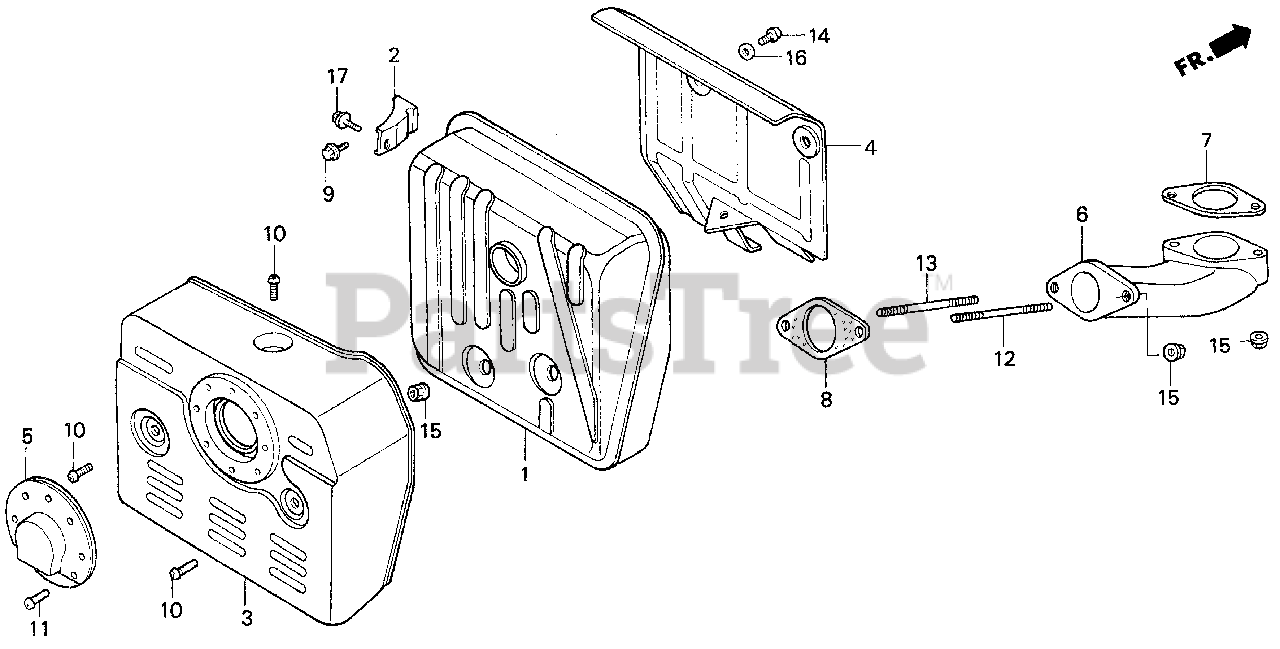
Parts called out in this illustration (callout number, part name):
1	MUFFLER
2	STAY, MUFFLER
3	PROTECTOR, MUFFLER
4	SEPARATOR, MUFFLER
5	CAP, MUFFLER
6	PIPE, EX.
7	GASKET, EX. PIPE (Honda Code 2108090). (NOT AVAILABLE)
7	GASKET, EX. PIPE
7	GASKET, EX. PIPE (WACKER)
8	GASKET, EX. PIPE (Honda Code 2278760). (NOT AVAILABLE)
8	GASKET, EX. PIPE
9	BOLT, FLANGE (8X16)
10	SCREW, TAPPING (5X8)
11	SCREW, TAPPING (4X6)
12	BOLT, STUD (8X60)
13	BOLT, STUD (8X70)
14	SCREW, PAN (6X6)
15	NUT, FLANGE (8MM)
16	WASHER, PLAIN (6MM)
17	BOLT, FLANGE (8X14)
